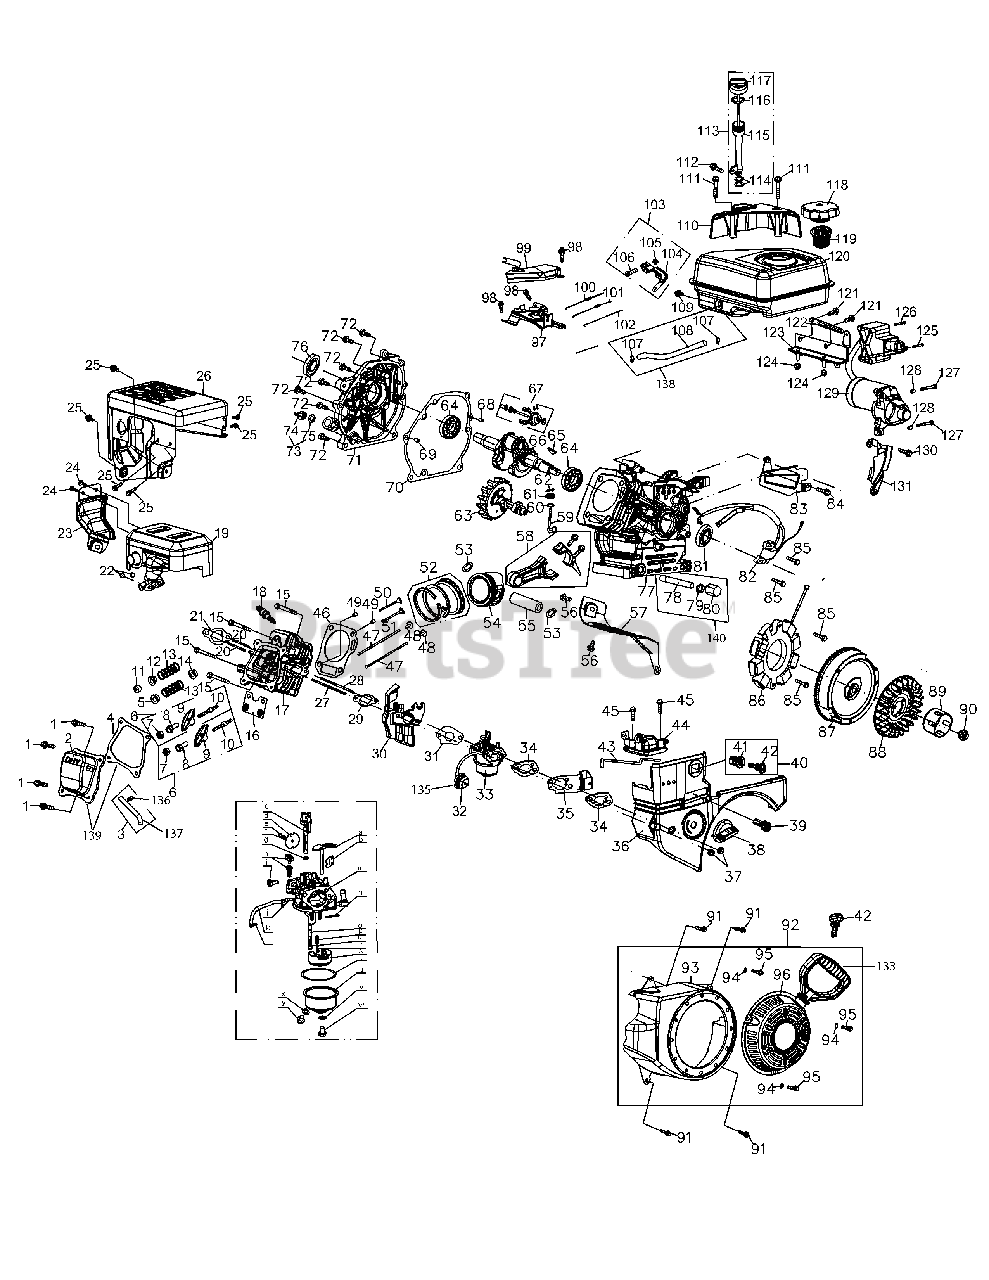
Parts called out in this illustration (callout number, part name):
1	Bolt M6×16
2	Valve Cover
3	Breather Hose
4	Valve Cover Gasket
5	Retainer, In.Valve Spring
6	Rocker Arm Assembly
7	Nut, Pivot Locking
8	Adjusting Nut ,Valve
9	Rocker Arm
10	Bolt, Pivot
11	Adjuster, Exh Valve
12	Retainer, Ex.Valve Spring
13	Valve Spring
14	Intake Valve Seal
15	Bolt M8×55
16	Push Rod Guide
17	Cylinder Head
18	Spark Plug/F6Rtc
19	Muffler Assembly
20	Muffler Stud Assy
20	Muffler Stud M8×36
21	Muffler Gasket
22	Nut, M8
23	Exhaust Pipe Shield
24	Bolt M6×10
25	Bolt M6×12
26	Muffler Shield
27	Stud M6×117
28	Stud M6×105
29	Carburetor Insulator Gasket
30	Carburetor Insulator Plate
31	Carburetor Gasket
32	Primer Assembly
33	Carburetor Assembly
34	Carburetor Gasket Plate
35	Choke Control Brkt
36	Engine Shroud
38	Choke Knob
39	Throttle Control Knob
40	Ignition Switch Assembly
41	Key Switch Base
42	Key
43	Choke Push Rod
44	Air Filter Heating Pipe Cvr.
45	Bolt M6×25
46	Gasket, Cylinder Head
47	Push Rod Kit
48	Tappet
49	Dowel Pin 10×16
50	Exhaust Valve
51	Intake Valve
52	Piston Ring Set
53	Piston Pin Snap Ring
54	Piston
55	Piston Pin
56	Bolt M6×12
57	Air Shield
58	Connecting Rod Assembly
59	Governor Arm Shaft
60	Washer 5.2×1.9
61	Governor Seal
62	Cotter Pin
63	Camshaft Assy.
64	Radial Ball Bearing, 6205
65	Woodruff Key
66	Crankshaft Assembly
67	Governor Gear/Shaft Assembly
68	Dowel Pin 7×14
69	Dowel Pin 9×14
70	Crankcase Cover Gasket
71	Cover Comp, Left Crankcase
72	Bolt M8×32
73	Oil Fill Plug Asm
74	Oil Filler Plug
75	O-Ring 15.8×2.5
76	Oil Seal, 25×41.25×6
77	Crankcase
78	Oil Drain Pipe
79	Washer 10×16×1.5
80	Oil Drain Plug Bolt
81	Oil Seal 25×41.25×6
82	Ignition Coil Assembly
83	Air Flow Shield
84	Bolt M6×10
85	Bolt M6×25
86	Stator
87	Flywheel
88	Fan, Cooling
89	Starter Cup
90	Nut, Special, M14×1.5
91	Bolt M6×12
92	Recoil Starter
93	Fan Cover - Blower Housing
94	Washer
95	Bolt M6×10
96	Recoil Starter
97	Throttle Control Asm
98	Bolt M6×12
99	Governor Shield
100	Governor Spring
101	Throttle Return Spring
102	Governor Rod
103	Governor Arm Assembly
104	Governor Arm Brkt
105	Nut M6
106	Governor Arm Bolt
107	Fuel Hose Clamp
108	Fuel Hose
109	Bolt M6×12
110	Engine/Dipstick Cover
112	Bolt M6×12
113	Dipstick Assembly
114	Oil Fill Tube O-Ring
115	Oil Fill Tube Assembly
116	Dipstick O-Ring
117	Dipstick Assembly
118	Fuel Cap Assembly
119	Fuel Level Indicator
120	Fuel Tank Assembly
121	Fuel Tank Nipple
121	Bolt M6×10
122	Flexible Clamp
123	Switch Housing Mounting Bracket
124	Nut, M6
125	Bolt M4×55
126	Bolt M4×60
127	Bolt M6×32
128	Dowel Pin 8×8
129	Electric Starter
130	Bolt M6×18
131	Blower Housing Shield
133	Starter Handle
135	Primer Bulb
138	Fuel Line Kit
139	Valve Cover Kit
140	Oil Drain Assembly
